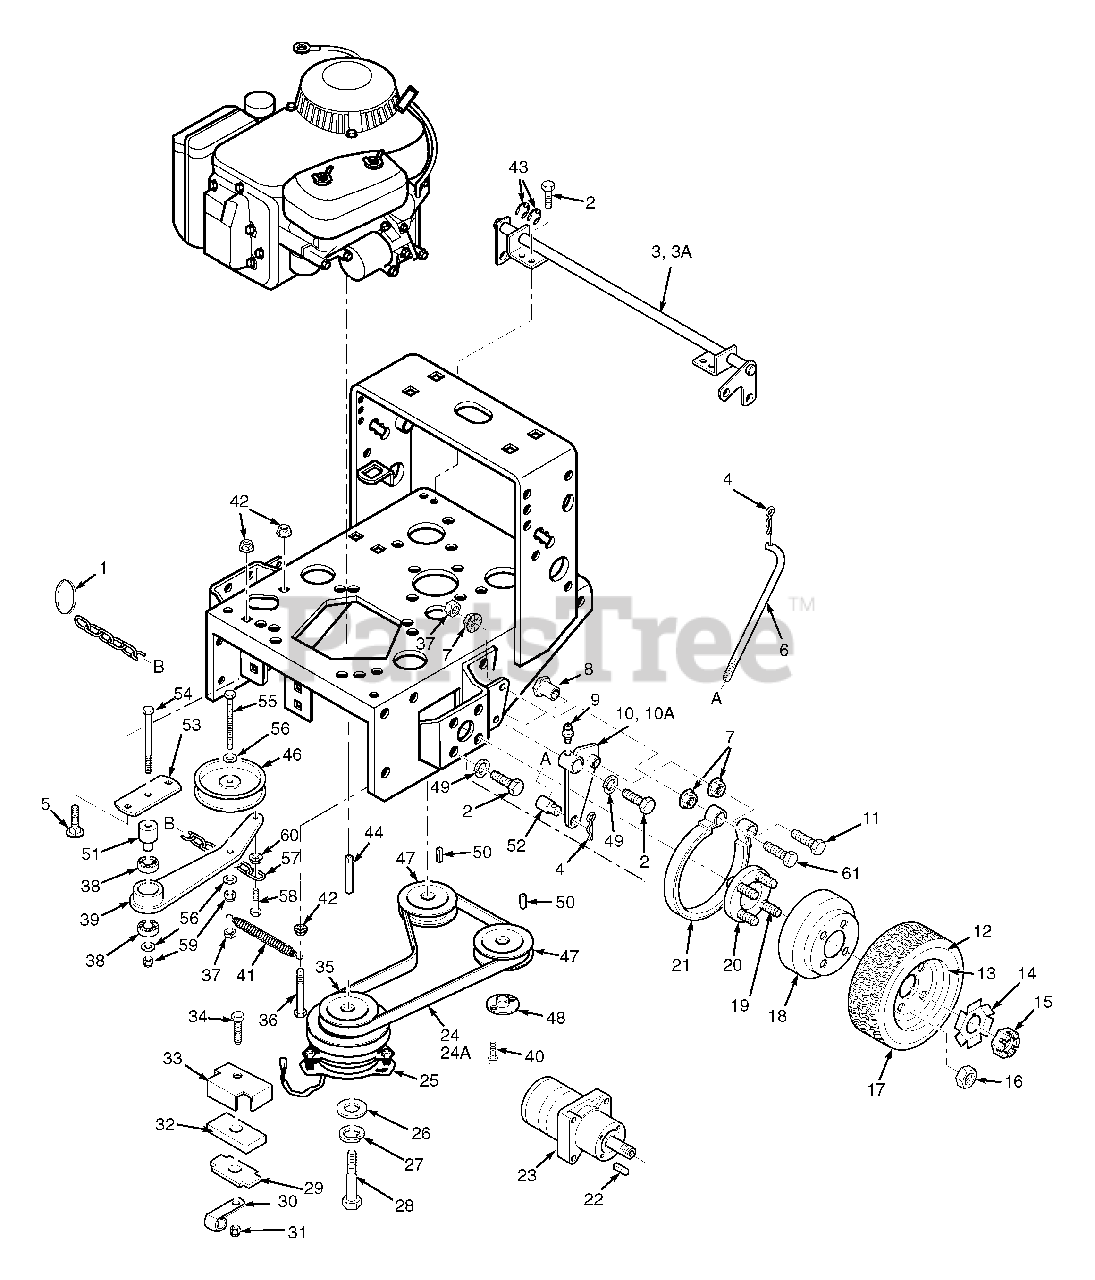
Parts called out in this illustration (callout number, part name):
1	Ring, Split
2	Bolt, 3/8-16 x 1" Hex Head
3	Brake Shaft Assembly Weldment (16" Small Frame)
3A	Brake Shaft Assembly Weldment (20" Large Frame)
4	Hair Pin Cotter, .094 x 1.62
5	Carrage Bolt, 5/16-18 x .75"
6	Rod, Brake Lower
7	Nut, 3/8-16 Serr. Flange
8	Bushing, Brake
9	Grease Fitting
10	Brake Actuator Wlmt., LH
10A	Brake Actuator Wlmt., RH
11	Bolt, 3/8-16 x 2-1/4"
12	Tire, 18 x 8.50, 4 ply
13	Rim Assy 481868 Rim Assy
14	Lock Washer, Wheel Motor
15	Hex Castle Nut, 3/4-28 UNEF
16	Nut, Lug
17	Wheel Assy., (incl. #12 & 13)
18	Brake Drum
19	1/2-20 Serrated Bolt
20	Hub, Wheel
21	Brake Band, 7.5"
22	Key, 3/16 X .75 Woodruff
23	Wheel Motor
24	Belt, Pump Drive (16" Small Frame)
24A	Belt, Pump Drive (20" Large Frame)
25	Electric Clutch
26	Flat Washer .469 x 1.75 x .25
27	Lock Washer, 7/16
28	Hex Head Bolt, 7/16-20 x 2-3/4"
29	Plate, Backing
31	Nut, 5/16-18 Elastic Stop
32	Rubber Pad, Clutch Stop
33	Retainer, Clutch Stop
34	Hex Head Bolt, 5/16-18 x 1.75"
35	Pulley, Pump Drive Engine
36	Hex Head Bolt, 5/16-18 x 2.75"
37	Nut, 3/8-16 Center Lock
38	Ball Bearings
39	Idler Arm Weldment, Pump (incl. 38)
40	Bolt, Hex Head 1/4-20 x 1" Grd 8
41	Spring, Pump Belt Idler
42	Nut, 5/16-18 Serr. Flange
43	Retaining Ring, 3/4" Ext. "E"
44	Key, 1/4x1/4 x 3.75"
45	Flat Washer, 3/8
46	Pulley, Idler 4.5"
47	Pulley, Pump Shaft
48	Tapered Hub
49	Lockwasher, 3/8
50	Key, 5.0 x 5.0 x 25mm
51	Pivot, Idler (Long)
52	Swivel Joint
53	Base, Idler Pivot
54	Bolt, Hex Head 3/8-16 x 3"
55	Bolt, Hex Head 3/8-16 x 2.75"
56	Flatwasher 3/8"
57	Chain
58	Bolt, Hex Head 1/4-20 x 1.25"
59	Nut, Hex Elastic Stop 3/8-16
60	Nut, Serrated Flange 1/4-20
61	Bolt, Hex Head 3/8-16 x 2.63"
